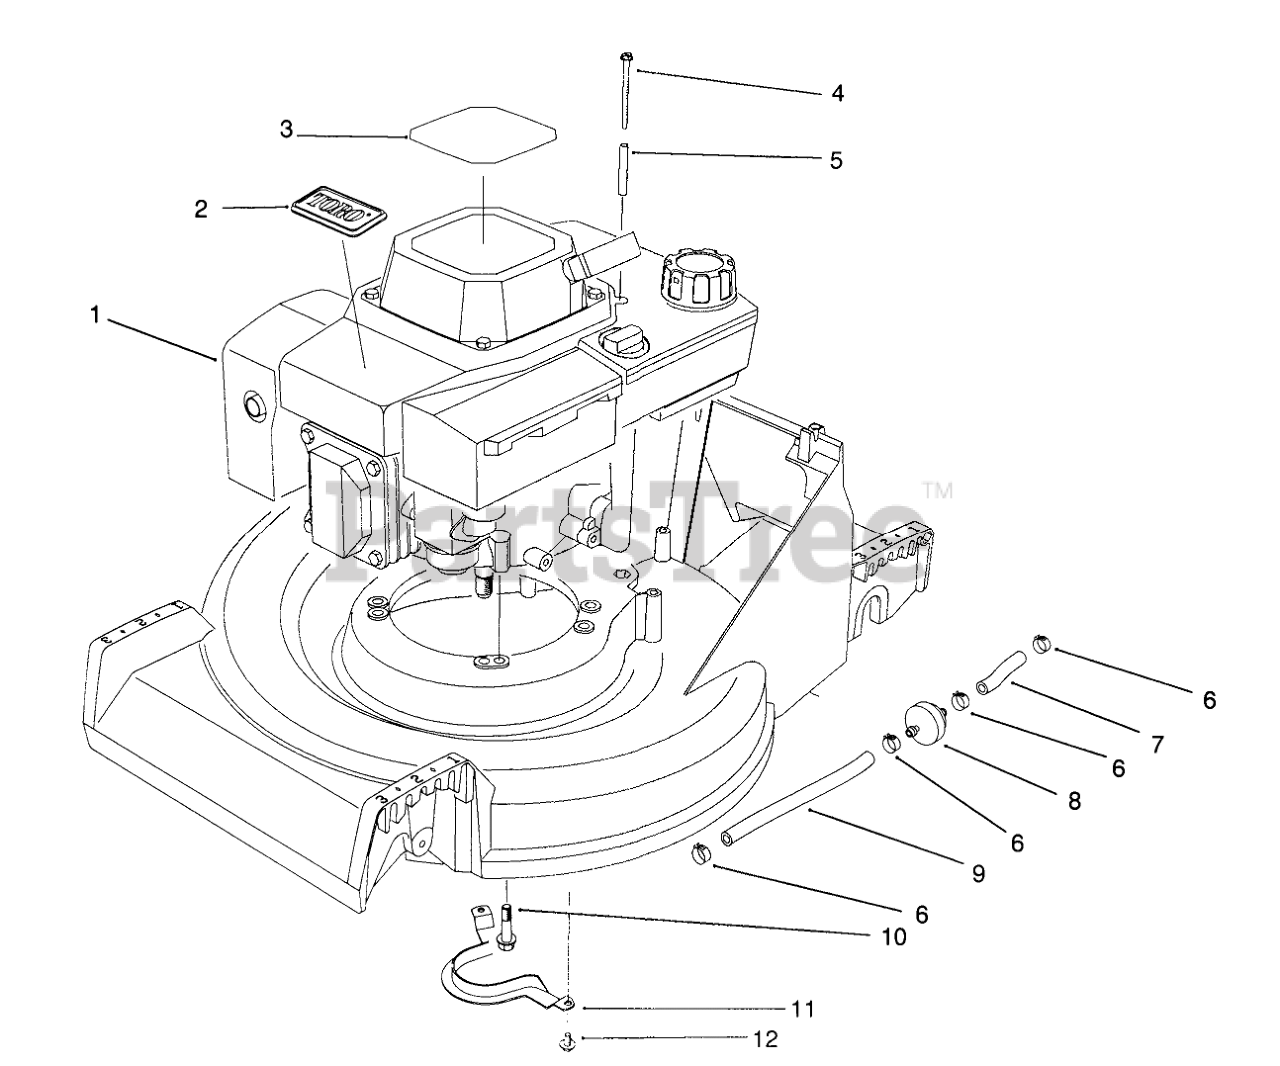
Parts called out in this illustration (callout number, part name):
1	ENGINE ASSY BBC OHV SU
2	TORO LOGO PLT
3	DECAL-HV INT'L
4	THRD FORMING SCREW
5	TUBULAR SPACER
6	CLAMP-FUEL LINE
7	LINE-GAS
8	FILTER-FUEL
9	HOSE-FUEL
10	SCREW-HWHTF
11	Guide-Belt
12	SCREW-HWHTF
